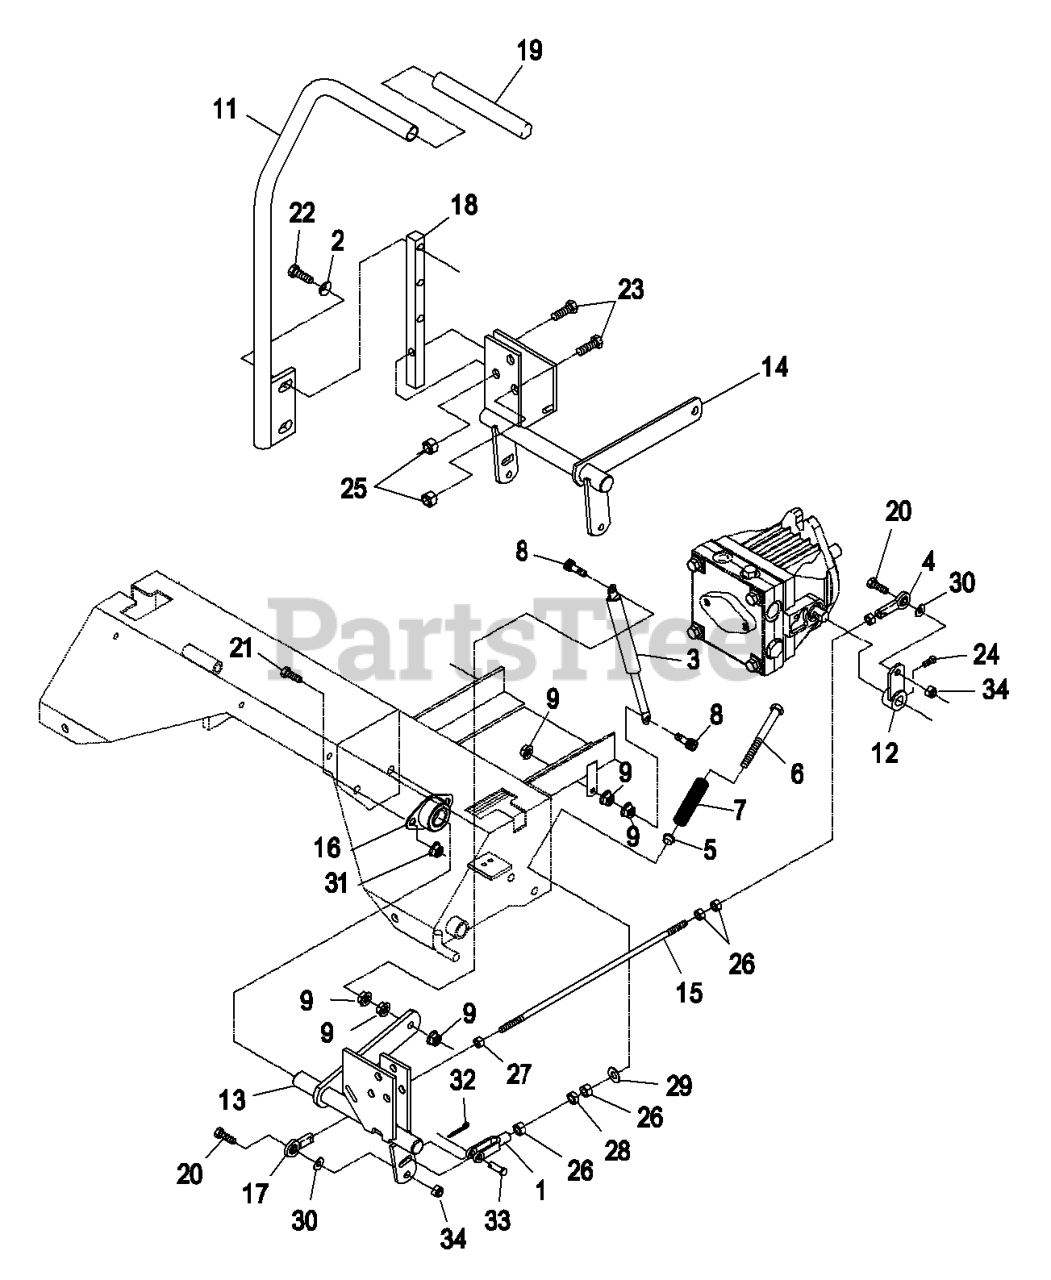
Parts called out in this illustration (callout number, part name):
1	YOKE-ADJUSTABLE
2	WASHER-BELLEVILLE
4	BALLJOINT-RH
5	BUSHING-FLANGED
6	BOLT-RETURN, NEUTRAL
7	SPRING-RETURN, NEUTRAL
8	SCREW-HH
11	RH LEVER ASM
12	ARM-CONTROL, PUMP
14	CONTROL-MOTION, RH
16	BEARING-FLANGE, SIDE
17	BALLJOINT-LH
18	ARM-SHAFT, CONTROL
19	GRIP-CONTROL, MOTION
20	SCREW-HH
21	SCREW-HH
22	SCREW-HH
23	SCREW-HH
24	SCREW-SET
25	NUT-LOCK, NI
26	NUT-HEX
28	NUT-JAM
29	WASHER-FLAT
30	WASHER-FLAT
31	NUT-HHF, WHIZ
32	PIN-COTTER
33	PIN-CLEVIS
34	NUT-LOCK, NI
